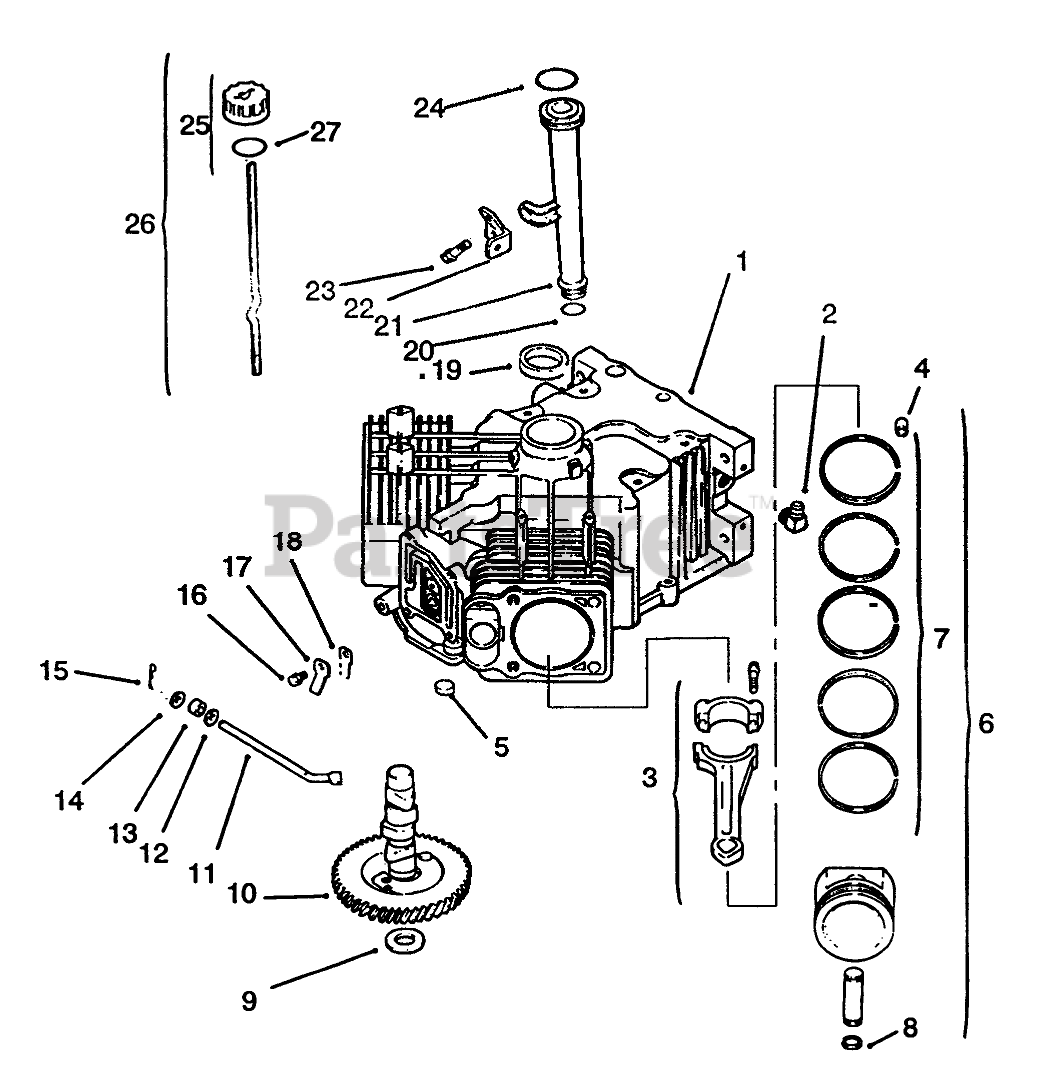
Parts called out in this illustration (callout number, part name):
1	Short Block (Only On: 72103, 72083)
2	Connector-90 DEG (Only On: 72103, 72083)
3	Connecting Rod STD (Only On: 72103, 72083)
3	Connecting Rod .25 (Only On: 72103, 72083)
4	Dowel-Locating (Only On: 72103, 72083)
5	Plug-Cup (Only On: 72103, 72083)
6	Piston ASM STD INC 4/7/8 (Only On: 72103, 72083)
6	Piston ASM .25 INC 4/7/8 (Only On: 72103, 72083)
6	Piston ASM .50 INC 4/7/8 (Only On: 72103, 72083)
7	Ring Set STD INC 4/8 (Only On:72103, 72083)
7	Ring Set .25 INC 4/8 (Only On: 72103, 72083)
7	Ring Set .50 INC 4/8 (Only On: 72103, 72083)
8	Retainer-Piston Pin (Only On: 72103, 72083)
9	Shim-Camshaft A/R (Only On: 72103, 72083)
9	Shim-Camshaft AIR (Only On: 72103, 72083)
10	Camshaft (Only On: 72103, 72083)
11	Shaft-Governor Cross (Only On: 72103, 72083)
12	Washer-Flat (Only On: 72103, 72083)
13	Seal-Governor Shaft (Only On: 72103, 72083)
14	Washer-Flat (Only On: 72103, 72083)
15	Pin-Governor Hitch (Only On: 72103, 72083)
16	Screw M5x0.8x10 (Only On: 72103, 72083)
17	Retainer-Reed (Only On: 72103, 72083)
18	Beed-Breather (Only On: 72103, 72083)
19	Seal-Oil (Only On: 72103, 72083)
20	O-Ring-Lower Fill Tube (Only On: 72103, 72083)
21	Tube-Oil Fill (Only On: 72103, 72083)
22	Bracket-Oil Fill Tube (Only On: 72103, 72083)
23	Screw M5x0.8x16 (Only On: 72103, 72083)
24	O-Ring-Upper Fill Tube (Only On: 72103, 72083)
25	Dipstick INC 26-27 (Only On: 72103, 72083)
26	Kit-Oil Cap INC 3 (Only On: 72103, 72083)
27	O-Ring-Fill Cap (Only On: 72103, 72083)
